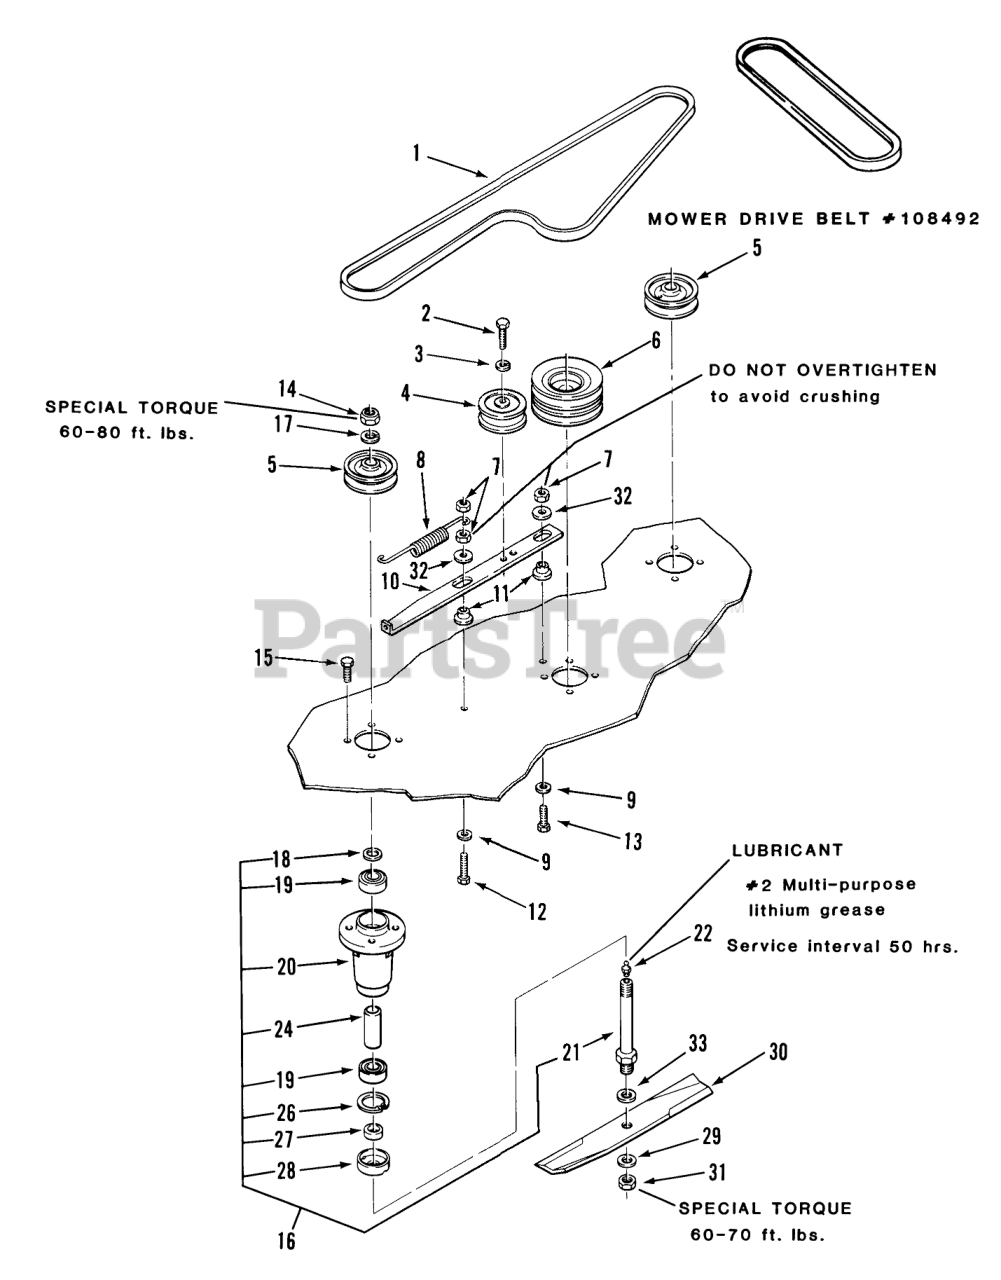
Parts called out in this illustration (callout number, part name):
1	V-BELT
2	BOLT HEX SPECIAL
3	LOCKWASHER
4	Idler Pulley
5	PULLEY
6	PULLEY CENTER
7	NUT
8	SPRING-EXTENSION
9	WASHER
10	BAR-IDLER SUPPORT
11	SPACER-BUSHING
12	Bolt
13	Bolt
14	Nut
15	Bolt
16	ASSY 36" SPINDLE
17	Lockwasher
18	Washer
19	BEARING-BALL
20	HOUSING-SPINDLE
21	Spindle Shaft
22	Zerk
24	Spacer
26	Ring-Snap
27	SPACER-BLADE
28	CUP-SPINDLE
29	SpeciaI Washer
30	S/A BLADE KIT
31	Nut
32	WASHER
33	Washer
